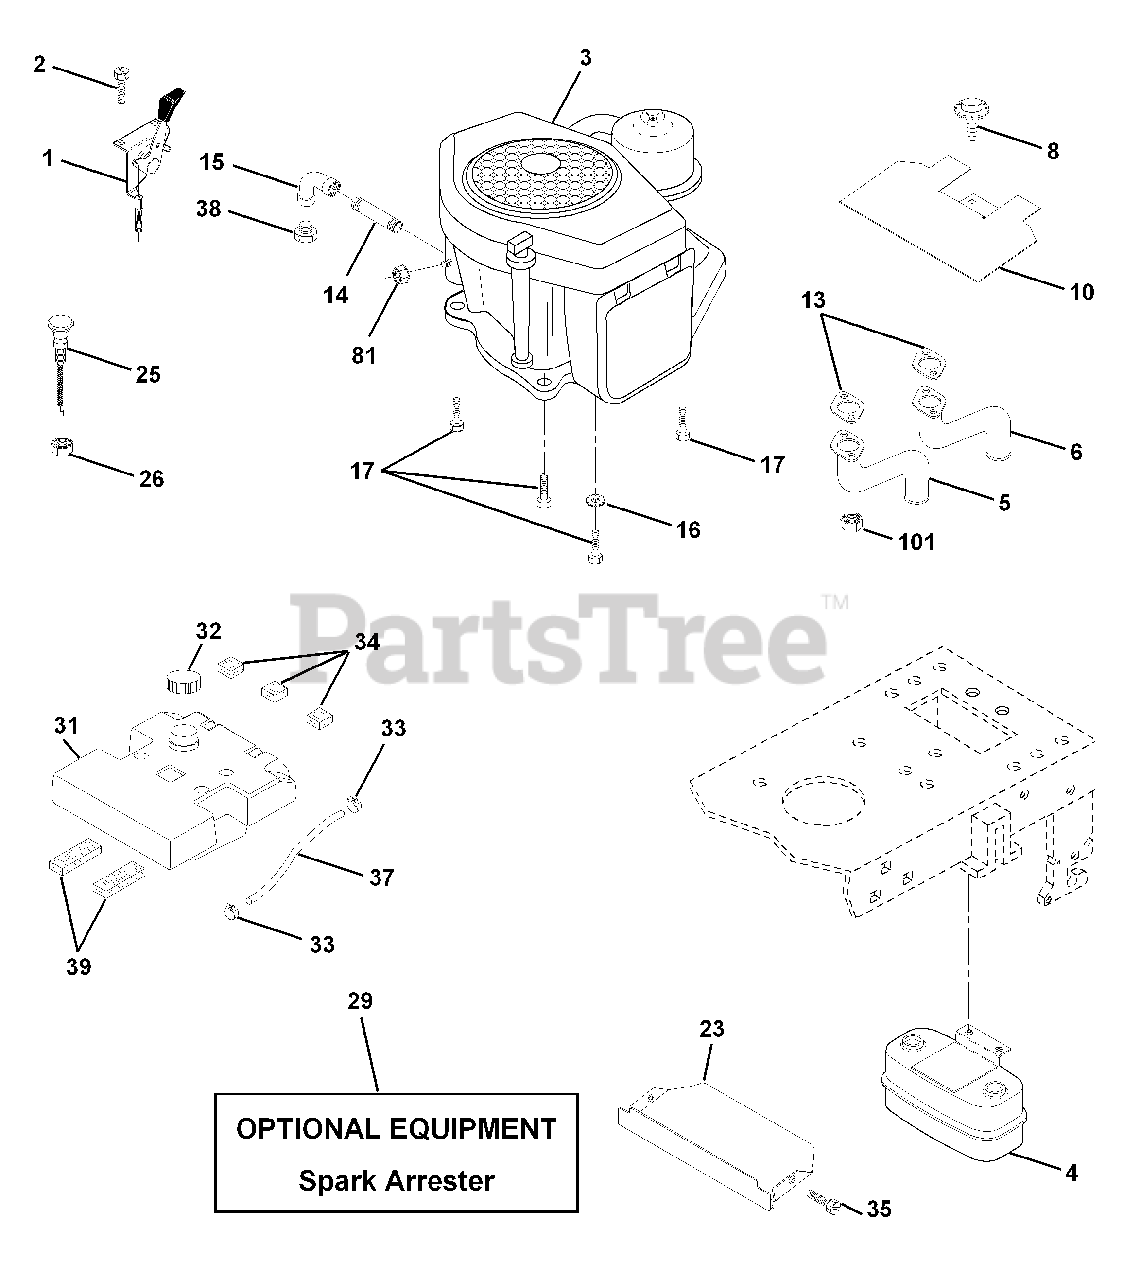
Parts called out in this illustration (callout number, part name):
1	Control Throt Flg 180 LH
2	Screw Hex Thd Cut 1/4-20x5/8 T
4	Muffler Asm Twin Lo-Tone
5	Pipe Exhaust CV18/20 LH
6	Pipe Exhaust CV18/20 RH
7	Clip, Fuel Line
8	Bolt 5/16-18unc x 3/4 W/Sems
10	Shield Heat Muffler CV18/20
13	Gasket Kohler CV18-CV26
14	Nipple Pipe 3/8 Npt X 4-1/2"
15	Elbow Std 90 Degree 3/8-18 Npt
16	Washer Lock Ext Tooth 3/8
17	Screw Thdrol 3/8-16 x 1-1/2
23	Shield Browning
25	Choke Control 37"
26	Nut, Keps 3/8-24 Unf
29	Kit Spark Arrestor
31	Tank Fuel 3 50 Rear
32	Cap Asm Fuel Top N/Lany Vented
33	Clamp Hose Blk
34	Pad, Spacer
35	Screw Thdrol 5/16-18 x 3/4
37	Line Fuel 7.5
38	Plug Oil Drain
39	Pad, Idler
40	Bushing
41	Stem Tank Fuel
81	Nut Flange 1/4-20 Starter Nut
101	Nut Flange M8-1.25 Non-Lk Zinc
